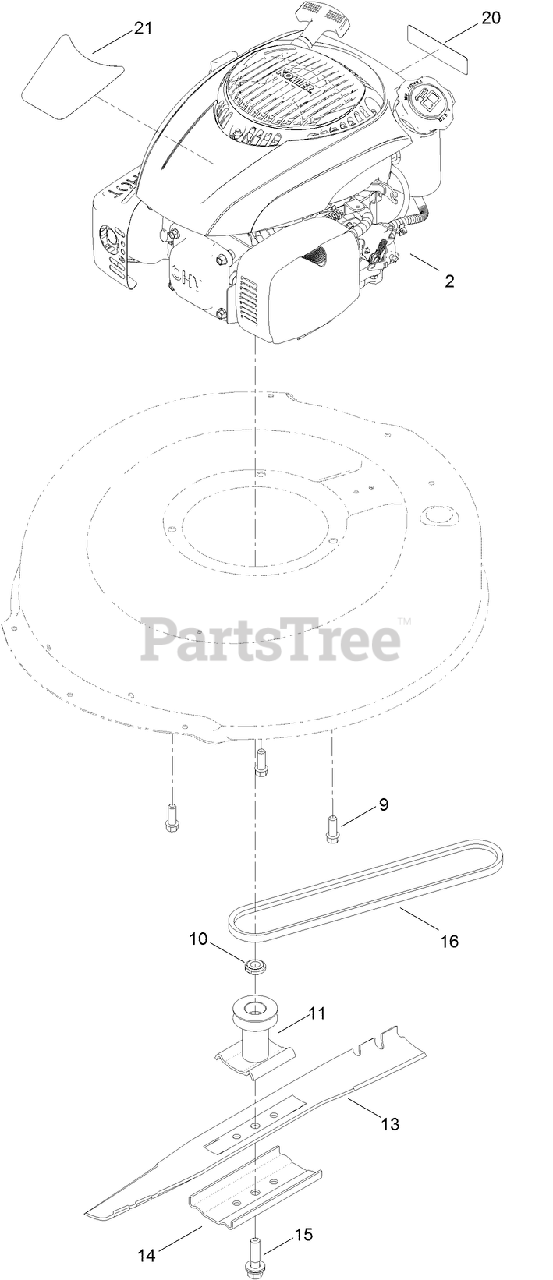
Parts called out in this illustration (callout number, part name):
9	SCREW-TAPTITE
10	SPACER-DRIVER
11	DRIVER-BLADE
14	SUPPORT-BLADE
15	BOLT-BLADE
20	DECAL-ARRESTER, SPARK
